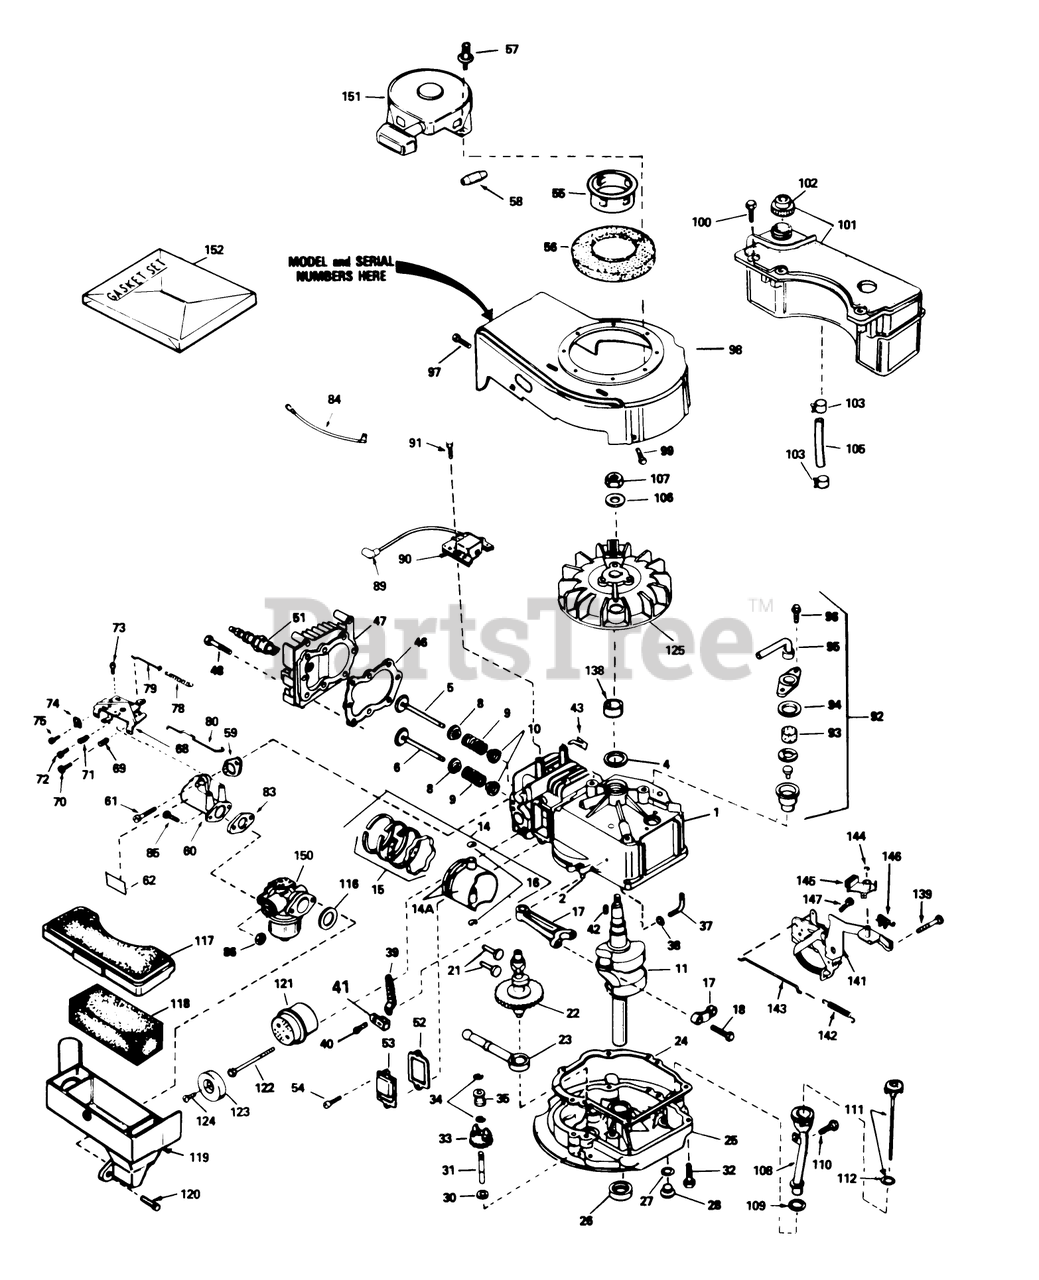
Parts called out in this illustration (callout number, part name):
1	Cylinder Assembly (Incl. Ref. #2, 4, 94 96)
2	Pin-Dowel
4	Seal-Oil
5	Valve, Intake (Std.) (Incl. Ref. #40)
5	Valve, Intake (1/32" oversize)(Incl. No. 40)
6	Valve, Exhaust (Std.)(Incl. No. 40)
6	Valve, Intake (1/32" oversize)(Incl. No. 40)
8	Cap-Upper Valve Spring
9	Spring-Valve
10	Cap-Valve, Spring
11	Crankshaft
14	Piston-Pin Ring Assy. (Std.)(Incl. Ref. #14A, 15 16)
14	Piston-Pin Ring Assy. (.010 oversize)(Incl. Ref. #14A, 15 16)
14	Piston-Pin Ring Assy. (.020 oversize)(Incl. Ref. #14A, 15 16)
14A	Piston Pin Assy. (Std)(Incl. Ref. #16)
14A	Piston Pin Assy. (.010 oversize) (Incl. Ref. #16)
14A	Piston Pin Assy. (.020 oversize) (Incl. Ref. #16)
15	Piston Ring Set Std.
15	Piston Ring Set .010 O.S.
15	Piston Ring Set .020 O.S.
16	Ring-Retaining, Piston Pin
17	Rod Assy., Connecting (Incl. Ref. #17)
18	Bolt-Rod, Connecting
21	Lifter-Valve
22	Camshaft(Mech.Comp. Release)
23	Oil Pump ASM
24	Gasket, Mounting
25	Flange Assy.-Mounting (Incl. Ref. #26, 27, 28 31)
26	Seal Oil
27	Gasket-Oil Drain
28	Plug Oil Drain
30	Washer-Flat
31	Shaft-Governor
32	Screw (1/4-20 x 1-1/4)
33	Governor Gear ASM
34	Ring-Retaining
35	Spool-Governor
37	Rod, Governor (Incl. No. 36)
38	Washer-Flat
39	Governor Lever
40	Screw
41	Clamp-Lever, Governor
42	Key-Flywheel
43	Clip-Wire
46	Gasket-Cylinder Head
47	2025A67 ADD.ASSEMBL
48	Screw (5/16-18x1-1/2)
51	Plug, Spark (Autolite 458, Champion J-19LM or equiv.)
52	Gasket-Breather
53	Cover-Valve
54	Screw
55	Cup-Starter
56	Screen-Starter
57	Pop Rivet (Can be purchased locally)
58	Retainer-Starter Rope
59	Gasket-Intake
60	Pipe-Intake (Incl. Ref. #59)
61	Screw (1/4-20 x 1)
62	Decal-Primer
68	51089 SUPP TO MANUA
69	61709/GIL1515A/95-5
70	Screw
71	Spring-Compression
72	Screw
73	Screw (10-24 x 9/16)
74	Conduit
75	Screw (10-32 x 3/8)
78	Spring Governor
79	2035A67 ADD.ASSEMBL
80	Link-Throttle
83	Gasket
84	Ground Wire
86	Nut and Lock Washer (1/4-28)
89	Cover-Spark Plug
90	Solid State
91	Screw
92	Breather Assy. (Incl. Ref. #46 thru 51)
93	Element-Breather
94	Gasket-Breather
95	Tube, Breaker
96	Screw (10-24 x 9/16)
97	Screw (10-24 x 9/16)
98	Housing-Blower
99	Screw (1/4-20 x 1/2)
100	Screw (10-32 x 35/64)
101	Tank Assembly-Fuel (Incl. Ref. #102)
102	Cap-Fuel
103	Clamp-Line, Fuel
105	Line-Fuel
106	Washer-Belleville
107	Nut-Flywheel
108	Tube-Oil Fill
109	Gasket
110	Screw (10-32 x 1/2)
111	Dipstick-Oil (Incl. Ref. #112)
112	O-Ring
116	Gasket-Cleaner, Air
117	Cover Air Cleaner
118	Filter-Air Cleaner
119	Body Air cleaner
120	Screw
121	Muffler (Incl. Ref. #122)
122	Screw
123	Cover-Muffler
124	Screw
125	Flywheel
138	Spacer
139	Screw (1/4-20 x 3/8)
141	Bracket Assy.
142	Spring-Extension
143	Link-Control
144	Ring-Retaining
145	Lever-Brake
146	Terminal
147	Screw-Hex. Hd.
150	Carburetor (Incl. Ref. #83)
151	tarter-Rewind
152	Gasket Set
